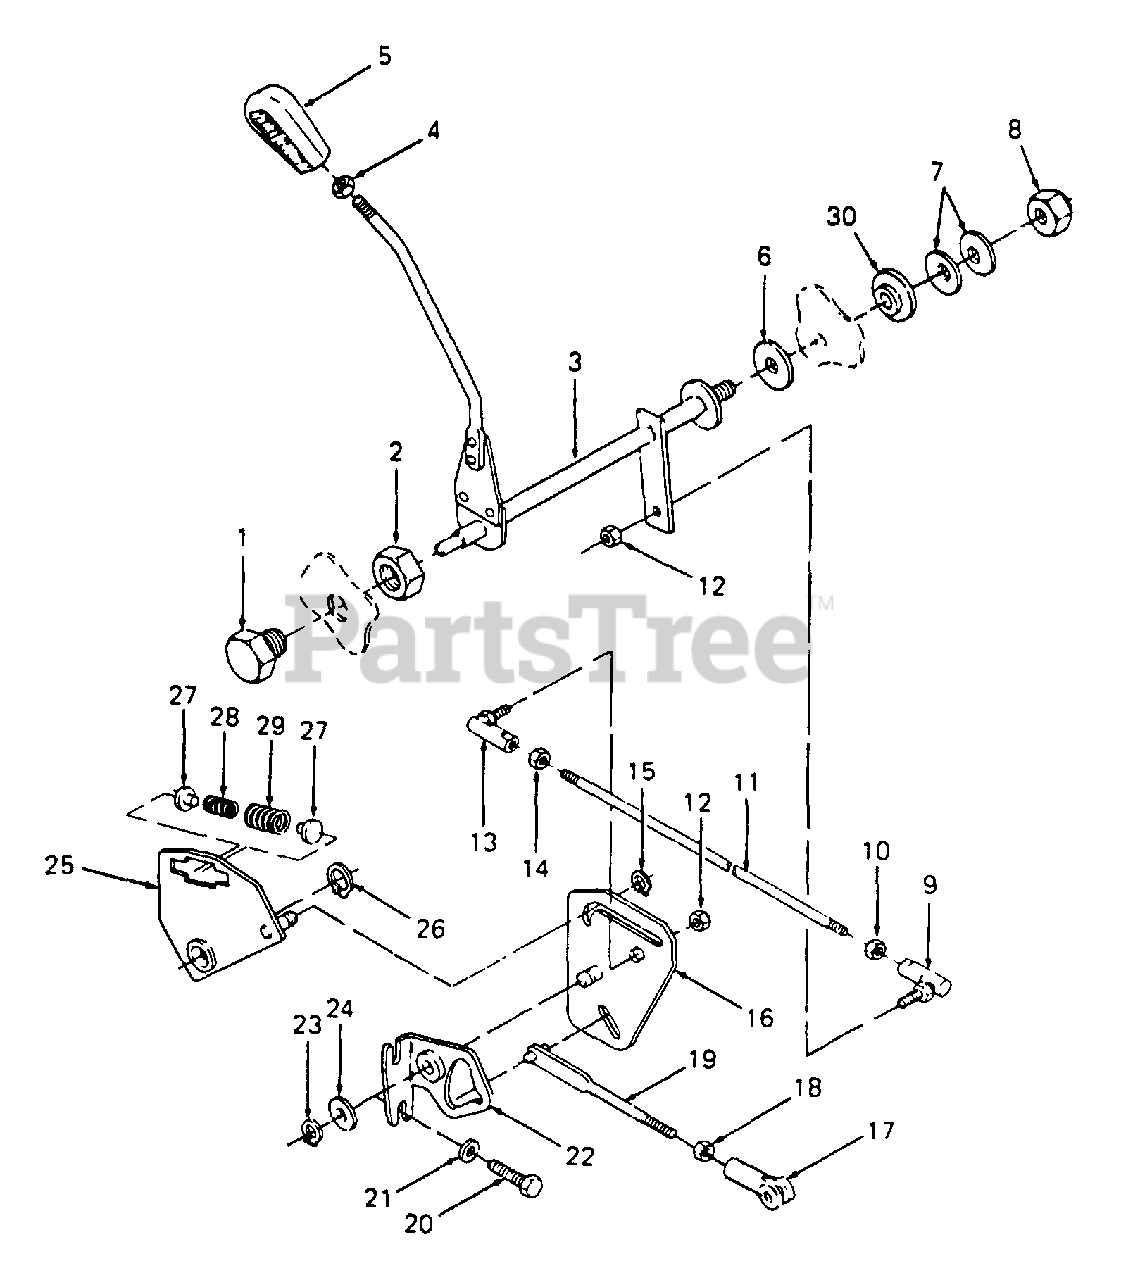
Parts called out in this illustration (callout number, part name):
1	Screw, Rockshaft Bearing, 3/4-16 x .75 Lg
2	Nut, Hex Jam, 3/4-16 GR5
3	Shaft Assy, Cross
4	Nut, Hex Jam, 3/8-16 GR5
5	Knob, Speed Control
6	Disc, Friction
7	Washer, Bell
8	Nut, Hex Top Lock, 1/2-20
9	Ball Joint, 5/16-24
10	Nut, Hex Jam, 5/16-24
11	Rod, Connecting
12	Nut, Hex Patch Lock, 5/16-24
13	Ball Joint, 5/16-24 LH Trd
14	Nut, Hex Jam, 5/16-24 LH Trd
15	Ring, Retaining, .375
16	Cam, Control
17	Clevis Adjustment
18	Nut, Hex Jam, 3/8-24 GR5
19	Rod, Control
20	Screw, Hex Cap, 3/8-16 x 1.5 Lg GR5
21	Washer, Flat, .385 x .87 x .06 Thk HDN
22	Bracket, Cam Pivot
23	Ring, Snap, .500
24	Washer, Flat, .510 x 1.0 x .060 Thk
25	Plate Assy, Damper Spring
26	Ring, Snap, .625
27	Pin, Spring Guide
28	Spring, Compression
29	Spring, Compression
30	Spacer, Shouldered
